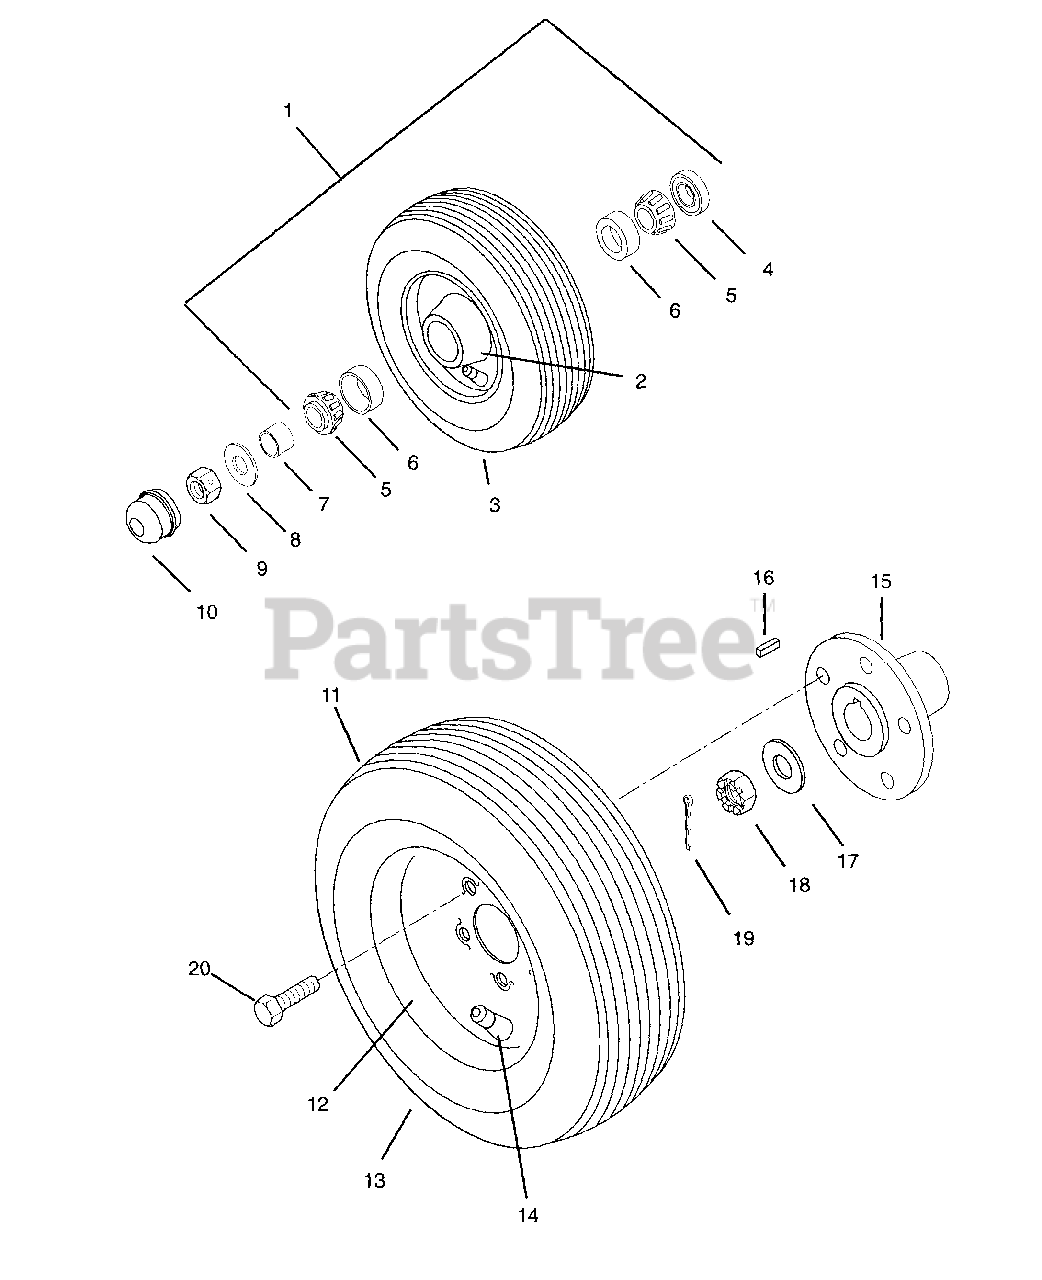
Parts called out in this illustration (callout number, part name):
1	Tire/ Wheel Assembly 15 - 6 x 6
2	Wheel Assembly
3	Tire 15 x 6-6
4	Seal 1.206 x 1.785 x .468
5	Bearing-Cone .750 x .61
6	Bearing-Cup 1.781 x .475
7	Spacer .752 x 1.000 x .500
8	Washer-Flat-Steel .656 x 1.31 x .095
9	Nut-Locking-Center.62-11
10	Dust Cap
11	Tire/Wheel Assembly 20-10 x 10
12	Wheel 10 x 7.50
13	Tire 20 x 10.00 - 10
14	Valve Stem Assembly
15	Hub, Wheel
16	Key-Feather .25 x 1.875 x .25
17	Washer-Flat-Steel .812 x 1.50 x .139
18	Nut-Slotted .75-16
19	Pin-Cotter .18 x 1.50
20	Bolt, Lug .44-20 x 1.00
